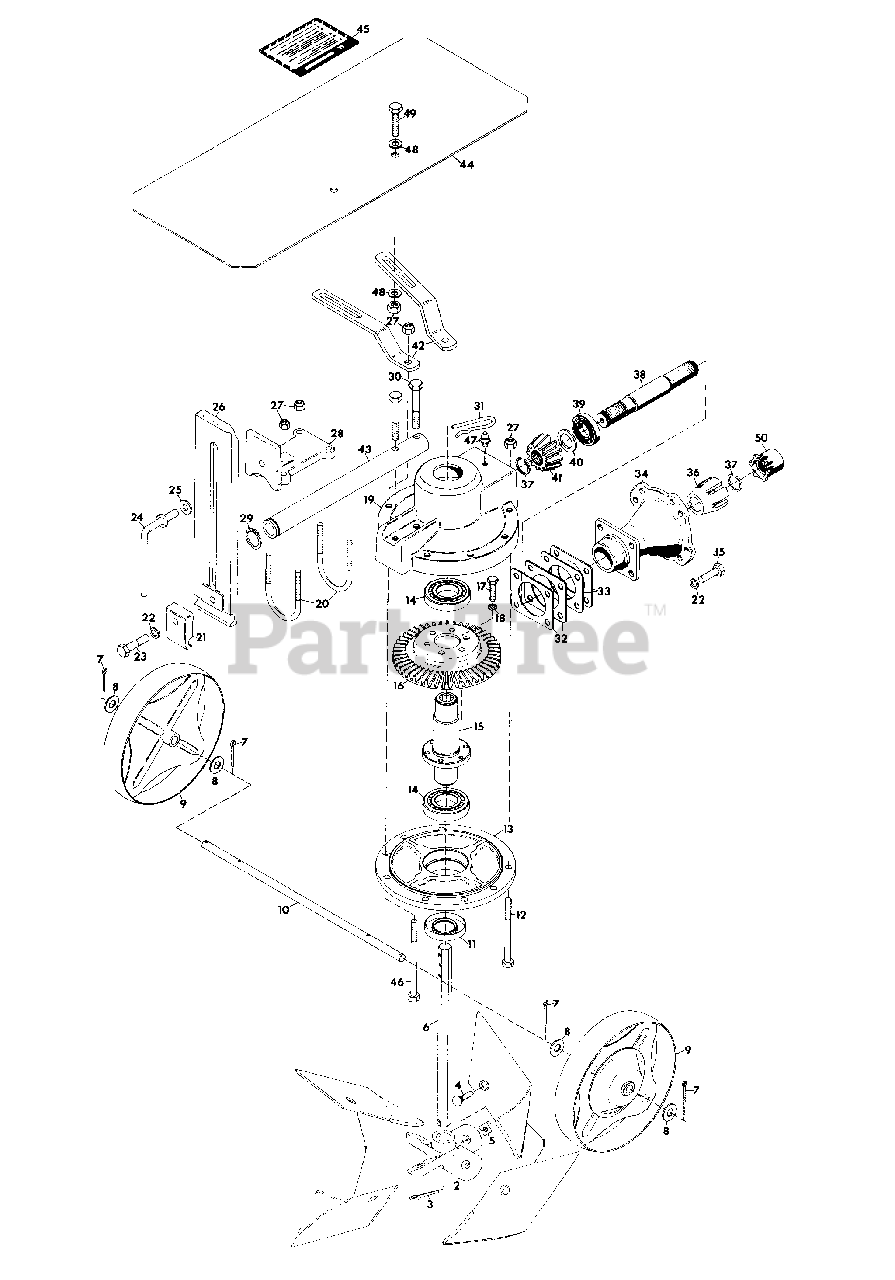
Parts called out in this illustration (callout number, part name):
1	BLADE, RIGHT SPADE
2	HUB, ROTOR
3	PIN, COTTER; .250 X 2.000
4	BOLT, PLOW; 1/2-13 X 1-1/2
5	NUT, SQUARE; 1/2-13
6	AXLE, ROTOR
7	PIN, COTTER; 3/16 X 1-5/8
8	WASHER, FLAT; .812 X 1.469 X .134
9	WHEEL, DEPTH
10	AXLE, DEPTH WHEEL
11	SEAL, OIL; 2.165 X 3.250 X .375
12	BOLT, HEX; 3/8-16 X 2-1/4
13	PLATE, GEAR HOUSING
14	BEARING, BALL; 2.155 X 3.543 X .709
15	HUB, BEVEL GEAR
16	GEAR, BEVEL
17	BOLT, HEX; 3/8-16 X 7/8
18	WASHER, LOCK; 3/8 SP
19	HOUSING, GEAR
20	U-BOLT; 3/8-16
21	CLAMP, AXLE
22	WASHER, LOCK; 1/2 SP
23	BOLT, HEX; 1/2-13 X 1-1/2
24	SCREW, WHEEL BRACKET CLAMP
25	WASHER, FLAT; 9/16 X 1-3/8 X .109
26	BRACKET, WHEEL
27	NUT, LOCK; 3/8-16 TYPE N HEX
28	SWIVEL, WHEEL BRACKET
29	RING, SNAP TRUARC 5160-193
30	BOLT, HEX; 1/2-13 X 2-3/4
31	PIN, DEPTH ADJUSTING
32	SHIM, .005
33	SHIM, .020
34	HOUSING, DRIVE SHAFT
35	BOLT, HEX; 1/2-13 X 1.25
36	CLUTCH, DOG
37	RING, RETAINING; .937 SHAFT
38	SHAFT, DRIVE
39	BEARING, BALL; .984 X 2.0472 X .590
40	RACE, THRUST; 1.002 X 1.552 X .155
41	PINION, BEVEL ROTARY PLOW
42	SUPPORT, SHIELD
43	SUPPORT, TUBE
44	SHIELD, DIRT
45	DECAL, CAUTION
46	BOLT, HEX; 3/8-16 X 2-1/2
47	FITTING, LUBE; 1/4-28
48	WASHER, FLAT; .406 X .812 X .065
49	BOLT, HEX; 3/8-16 X .750
50	DOG, ATTACHMENT
